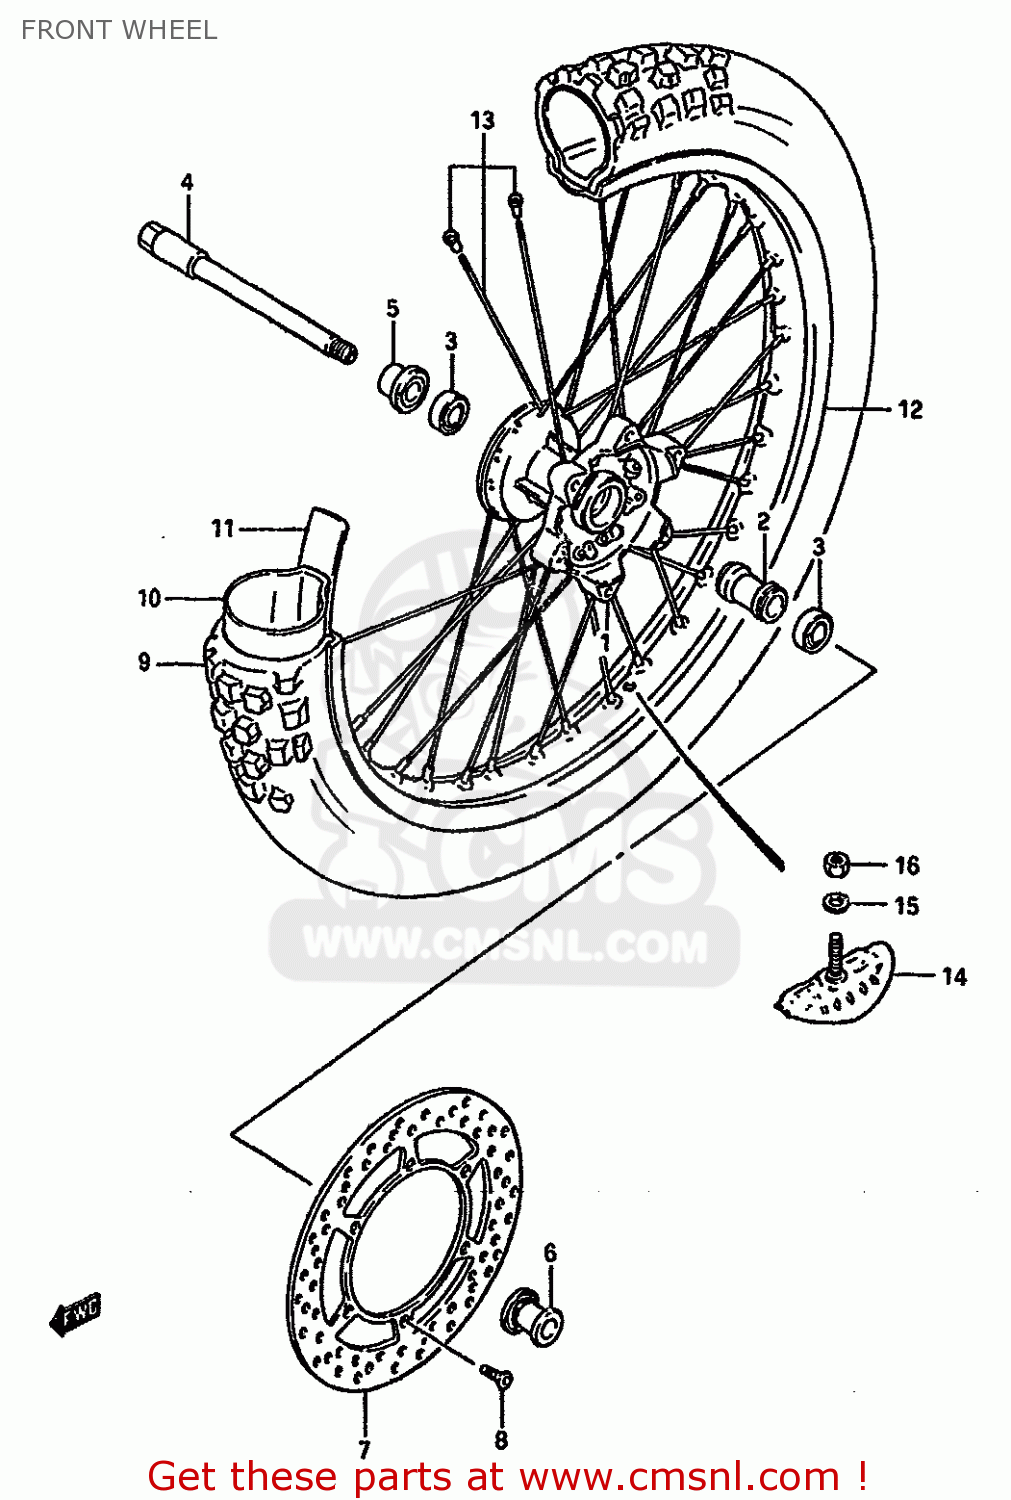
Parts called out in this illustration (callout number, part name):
1	HUB,FRONT
2	SPACER,FR HUB BEARING
3	BEARING
4	AXLE,FRONT
5	SPACER,FRONT AXLE,RIGHT
6	SPACER,FRONT AXLE,LEFT
7	DISC,BRAKE
8	SCREW
9	TIRE,FRONT
10	TUBE,INNER
11	PROTECTOR,WHEEL INNER
12	RIM,FRONT WHEEL
13	SPOKE SET,FRONT
14	STOPPER,BEAD
15	WASHER
16	NUT 8MM
